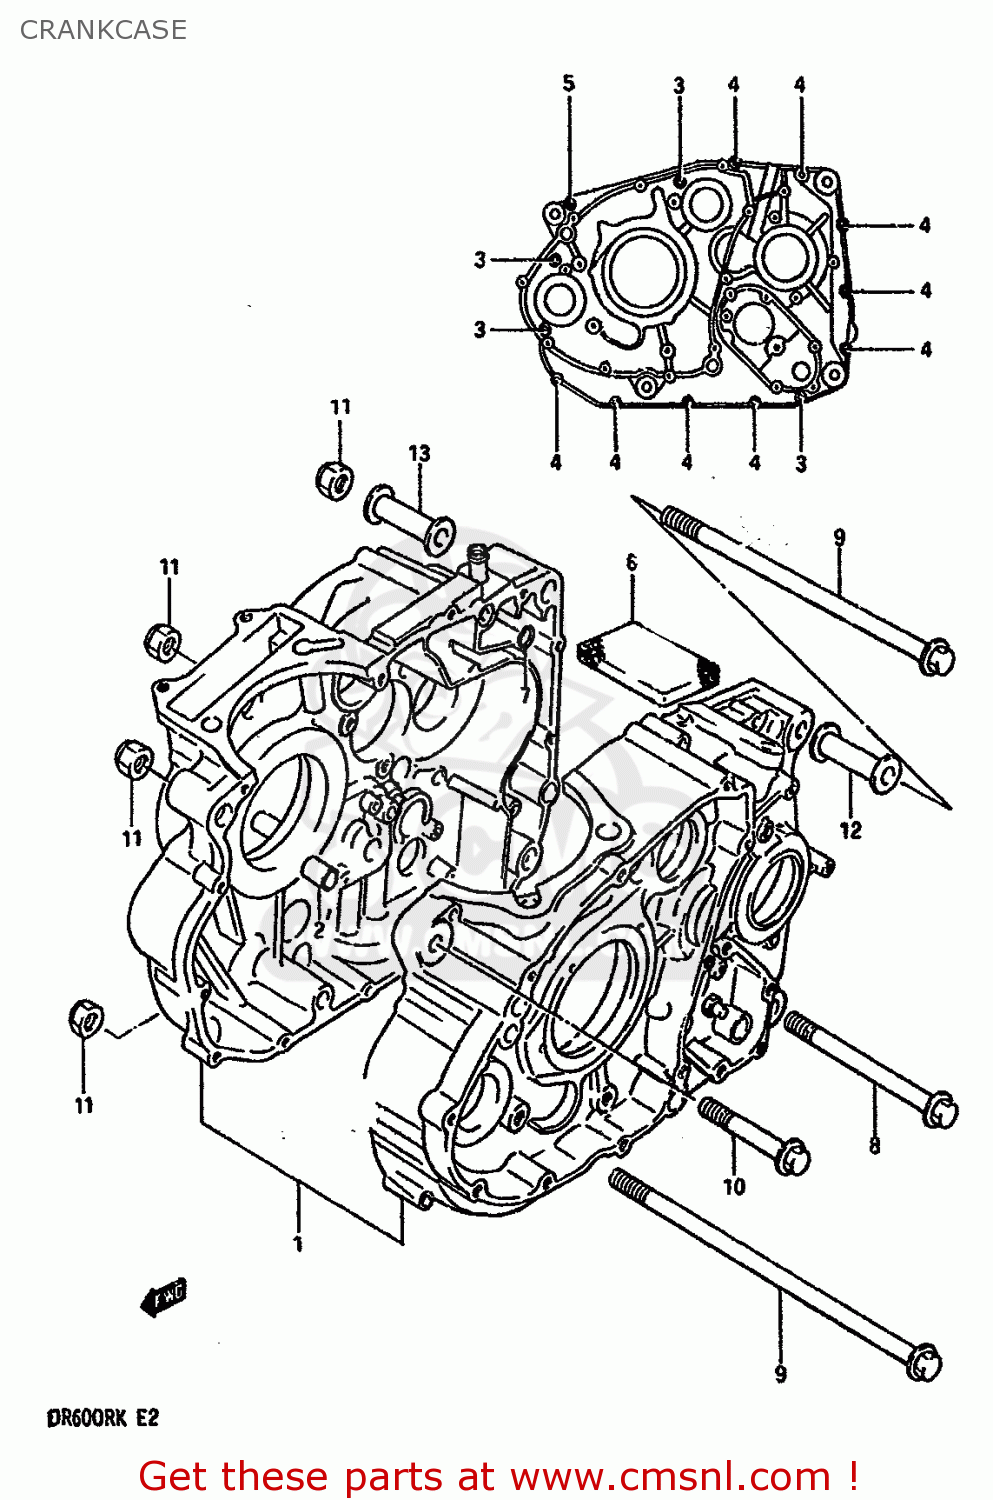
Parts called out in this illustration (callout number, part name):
1	CRANKCASE SET
2	PIN
3	BOLT (6X60)
4	BOLT 6X40
5	BOLT 6X30
6	HOSE
7	O-RING
8	BOLT(10X125)
9	BOLT
10	BOLT
11	NUT
12	SPACER,ENG MTG(L:55)
13	SPACER,ENG MTG,R(L:60)
